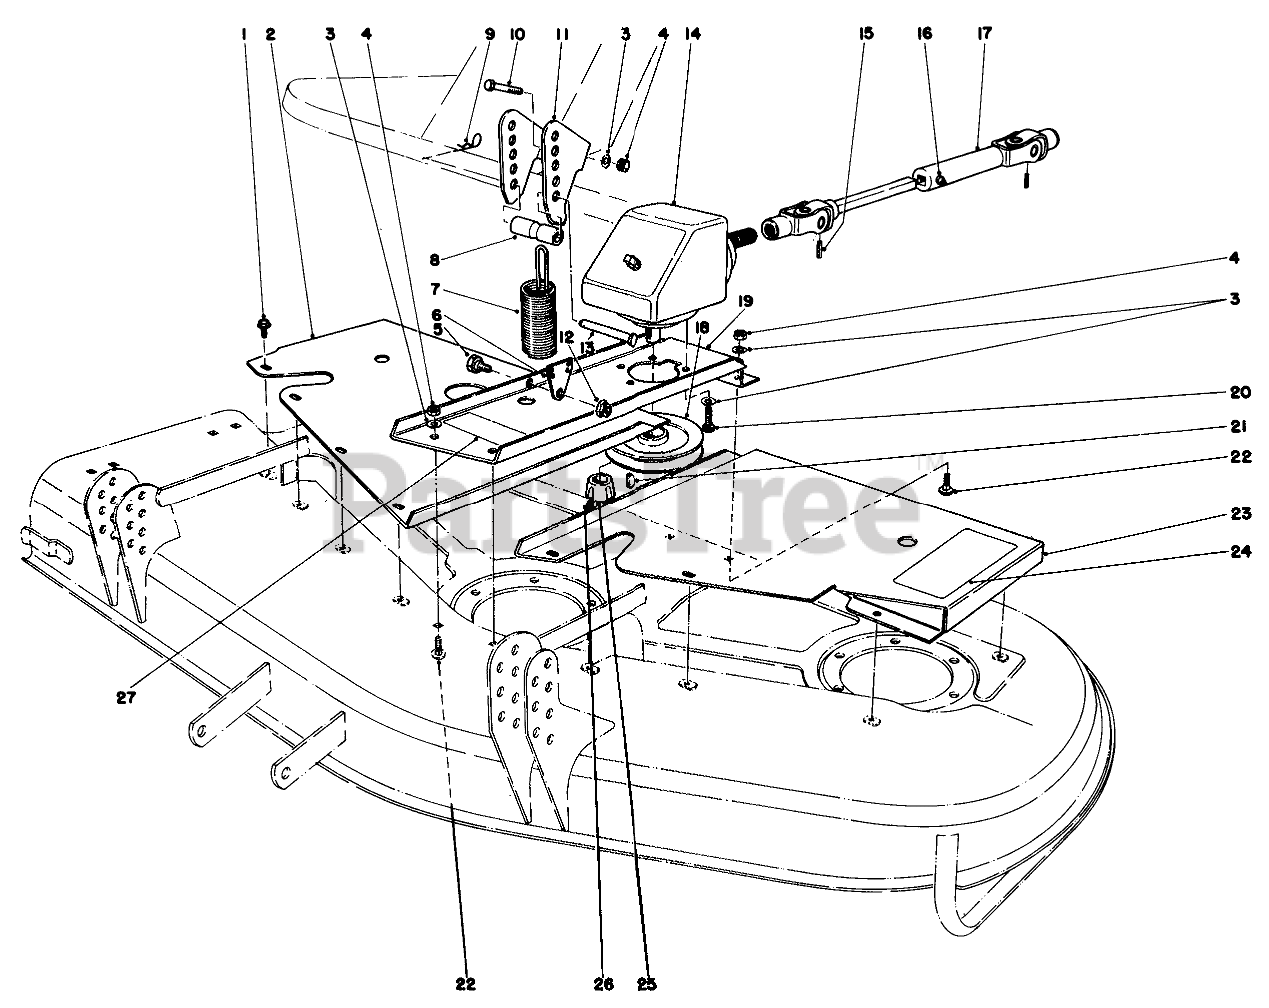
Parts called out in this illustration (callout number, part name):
1	SCREW-HHFTF
2	RH COVER WA R
3	WASHER-LOCK
4	NUT-HEX
5	BOLT-SHOULDER
6	SPRING END R
7	Spring-Extension
8	SPACER
9	PIN-HAIR
10	SCREW-HH
11	SPRING BRACKET R
12	NUT-HHF, WHIZ
13	PIN-CLEVIS
14	Gear Box Assembly
15	PIN-ROLL
16	FITTING-GREASE
17	UNIVERSAL JOINT
18	PULLEY WA BO
19	Base-Bear Box
20	SCREW-HSH
21	KEY-WOODRUFF
22	SCREW-CARR
23	LH COVER WA R
24	DECAL
25	BUSHING-LOCK, TAPER
26	SCREW-SET, HSH
27	Decal-Caution
